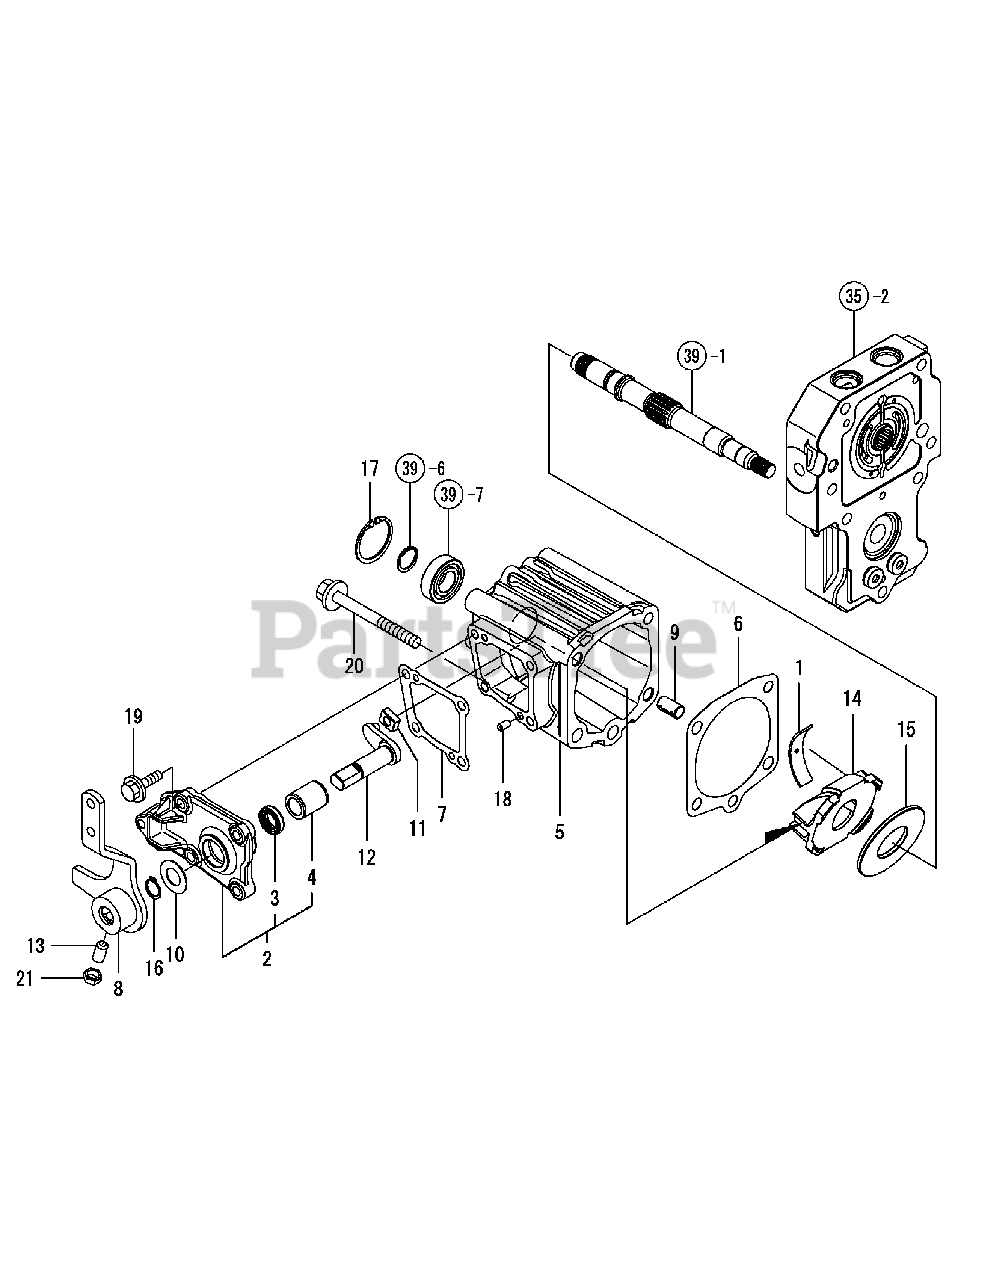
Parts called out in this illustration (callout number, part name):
1	THRUST METAL (DDR16)
2	SIDE COVER CMP
3	SEAL TC16 26 6, OIL
5	MOTOR CASE K93
6	PACKING, MOTOR CASE
7	PACKING (SIDE COVER)
8	SECOND LEVER CMP
9	PIN 12X22, KNOCK
10	WASHER 17X32X1
13	SET SCREW 10X20
18	PARALLEL PIN, M6X10
19	BOLT M 8X 30 PLATED
20	BOLT M10X105 PLATED
21	LOCK NUT M10 PLATED
